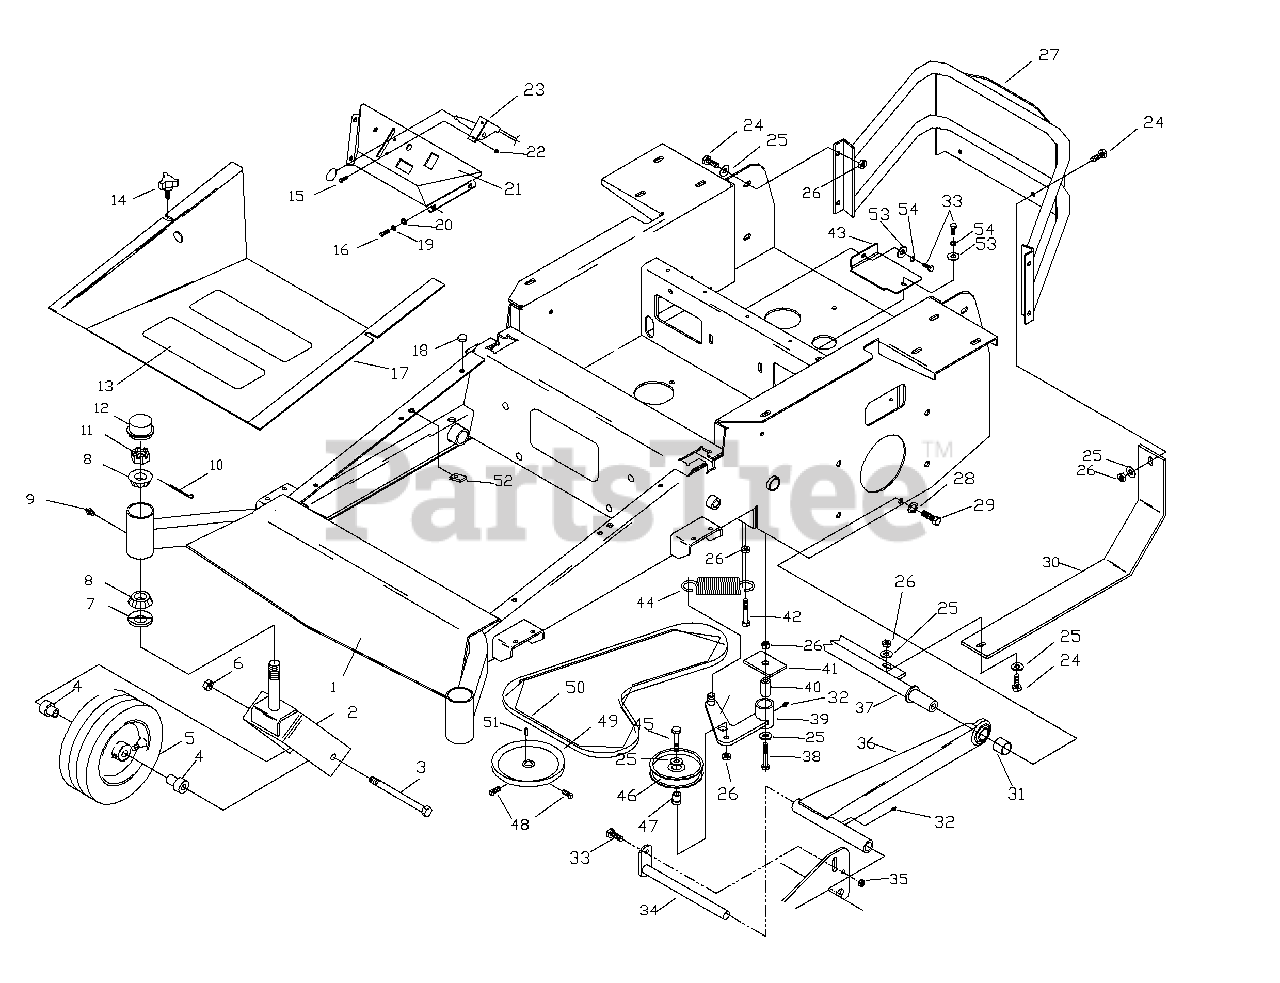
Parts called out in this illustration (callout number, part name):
1	FRAME
2	CASTER YOKE
3	HCS 1/2 X 9.5
4	AXLE SPACER
5	WHEEL ASM.
5	ZERK
5	BEARING, TAPERED
6	NUT 1/2 NYLOC
8	BEARING, TAPERED
10	COTTER PIN 1/8 X 2
11	NUT 1.0 CASTLE
12	GREASE CAP
13	ANTI SKID PAD
14	KNOB
15	HCS # 10 X 1/2
16	1/4 x 5/8 SELF TAP
17	FOOT PLATE
19	1/4 LOCK WASHER
20	1/4 FLAT WASHER
22	NUT #10 NYLOC
23	THROTTLE CABLE
24	HCS 3/8 X 1.0
25	3/8 FLAT WASHER
26	NUT 3/8 LOCK
27	ENGINE GUARD
28	7/16 LOCK WASHER
29	HCS 7/16 X 1.0 GD 8
30	SKID PLATE
31	STRUT SPACER
32	ZERK
33	HCS 5/16 X 3/4
35	NUT 5/16 LOCK
37	CROSS SHAFT
38	HCS 1/2 X 3.25
39	IDLER ARM
40	PIVOT BUSHING
41	SUPPORT PLATE
42	HCS 3/8 X 1.5
43	IDLER COVER
45	HCS 3/8 X 1.75
46	IDLER PULLEY
47	IDLER BUSHING
48	5/16 X 5/8 SETSCW.
50	PUMP BELT
51	KEY 5mm SQ.
53	5/16 FLAT WASHER
54	5/16 LOCK WASHER
55	STRUT RT. SIDE
56	STRUT PIN RT. SIDE
57	STRUT SPACER RT.SIDE
